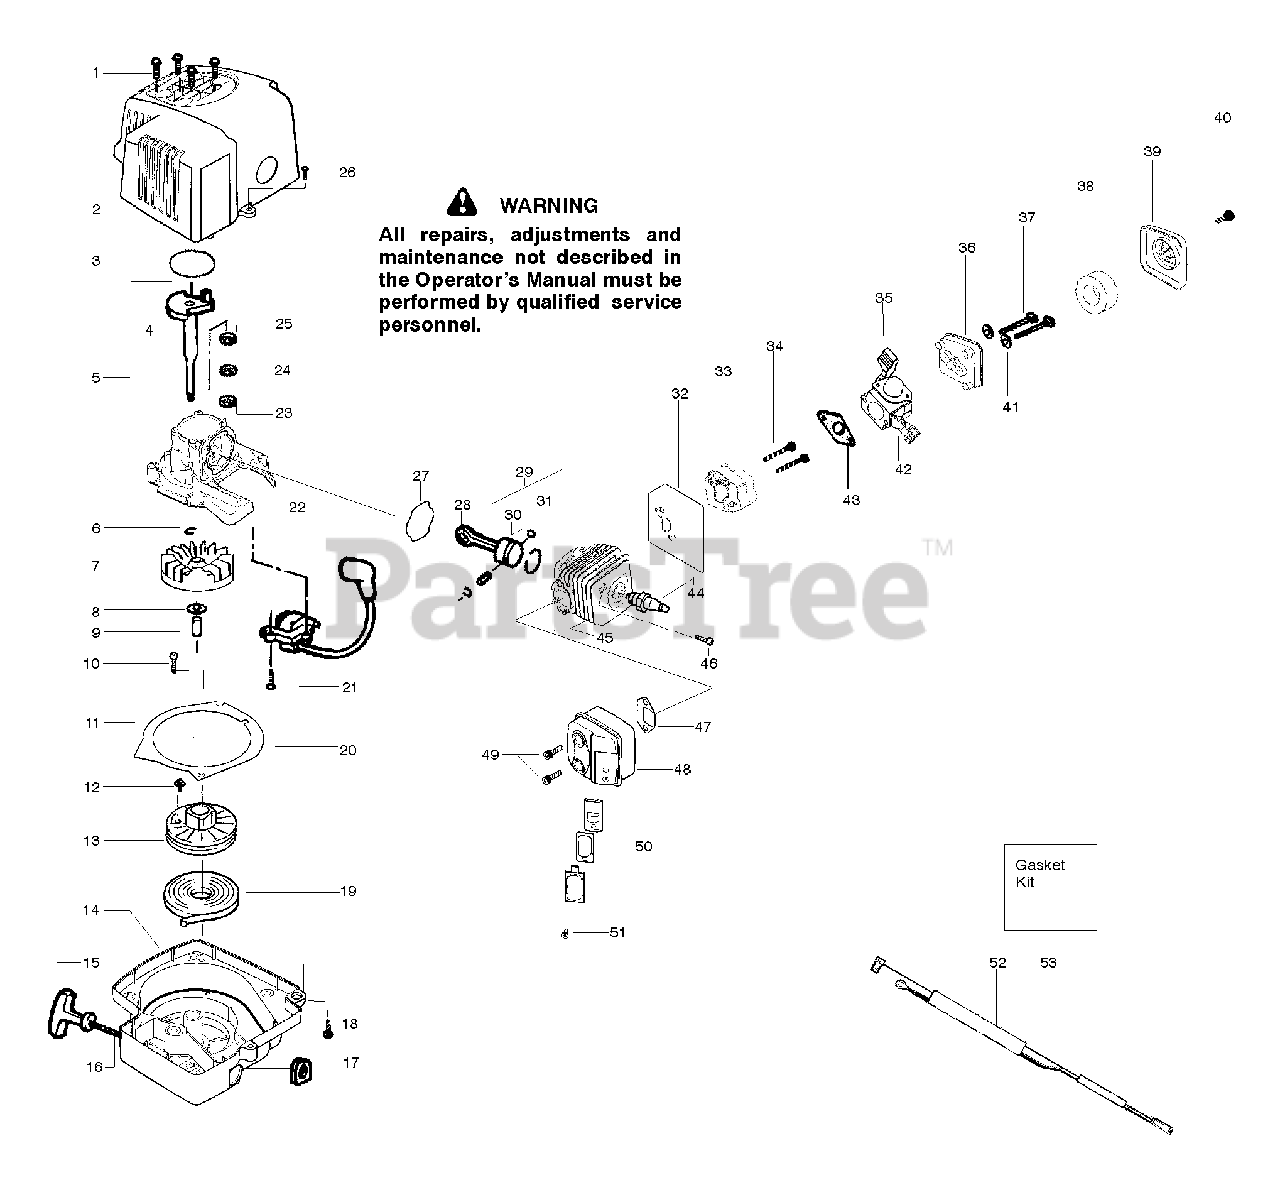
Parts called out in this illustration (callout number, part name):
2	Assy-Shroud/H'shield
3	O-Ring-C'case
4	Assy-Crankshaft
5	Assy-C/case-C/shaft
6	Ring-Retainer-C'shaft
7	Assy-Flywheel
8	Washer-Flat
9	Spacer-Flywheel
11	Plate-Baffle
13	Kit-Starter Pulley
14	Assy-Fan Housing
15	Handle-Starter
16	Kit-Rope
17	Grommet-Ignition Module
18	Screw
19	Spring-Starter
21	Ignition Module
22	Assy-Crankcase
23	Bearing-Outer
24	Seal-Crankcase
25	Bearing-Inner
27	Seal-Cylinder
28	Assy-Connecting Rod
29	Kit-Piston
30	Retainer-Piston Pin
31	Ring-Piston
32	Gasket-Carb. Adapt.
33	Adapter-Carburetor
35	Kit-Choke Lever
38	Air Filter Foam
39	Air Filter Cover
41	Washer
42	Kit-Carburetor Ass'y.
43	Gasket-Carburetor
44	Spark Plug
45	Cylinder
47	Gasket-Muffler
48	Kit-Muffler
49	Bolt-Muffler
50	Kit-Spark Arrestor
52	Assy-Leadwire
53	Kit-Gasket
